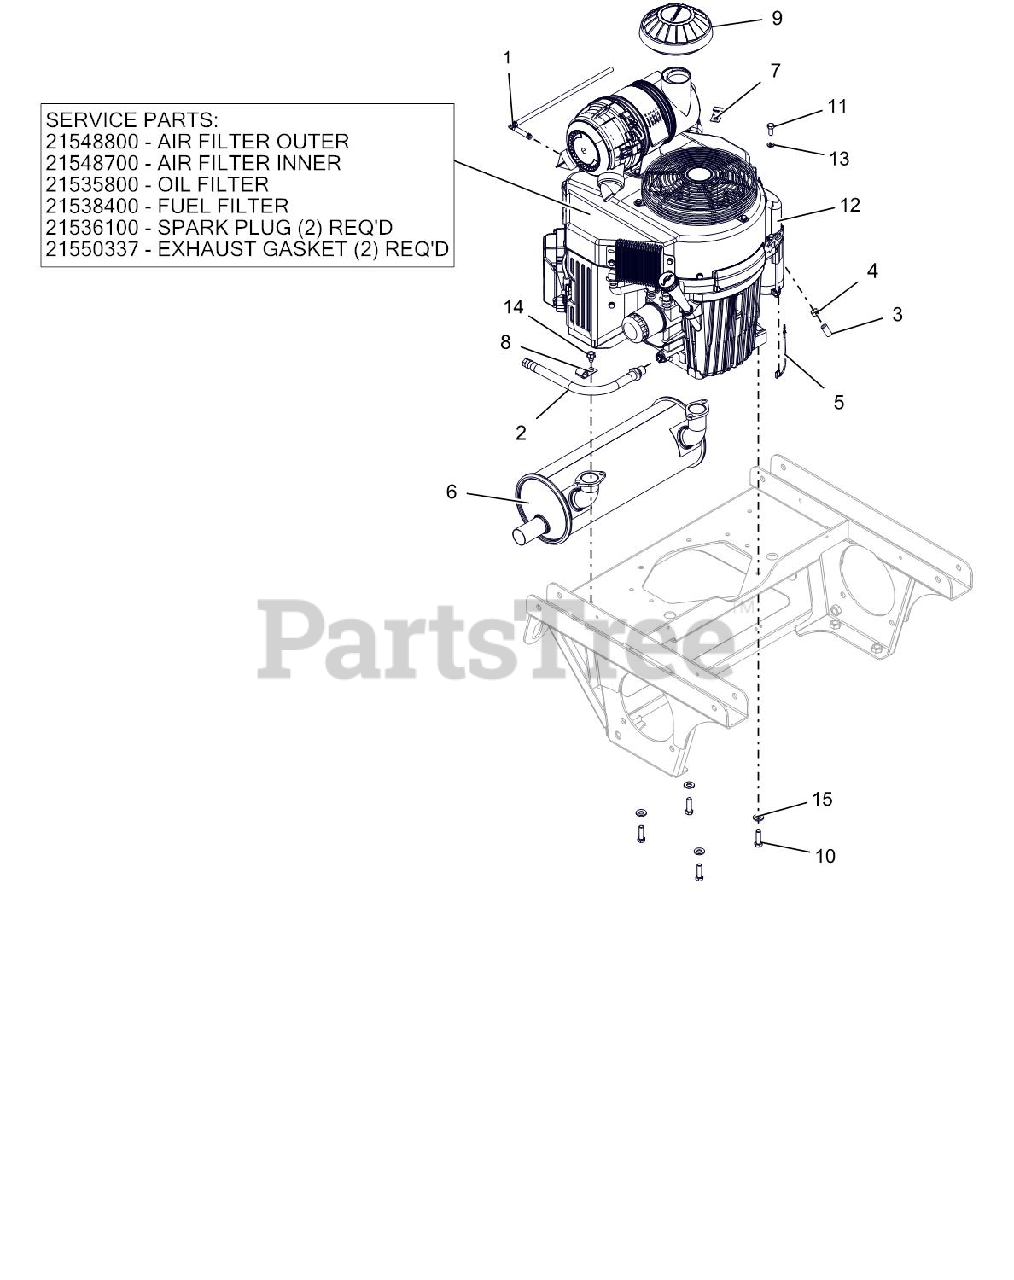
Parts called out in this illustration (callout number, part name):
1	ASM, VAPOR LINE
2	HOSE, OIL DRAIN
3	HOSE, .25 LOW-PERM BULK GAS
4	CLAMP, FUEL LINE
5	LEAD - STARTER SOLENOID
6	MUFFLER - 34HP KAWASAKI VERT.
9	CAP, AIR CLEANER INTAKE (2")
10	BLT-HEX.38-16X1.25 G5YZ NYTORQ
11	@BLT-HEX M8-1.25X20 YWZC
12	FILTER,OIL - KAW
12	PLUG, SPARK
12	FUEL FILTER - KAWASAKI
12	FILTER, OUTER
12	FILTER, INNER - KAW
12	ENGINE - KAWASAKI FX1000
12	GASKET, EXHAUST (11061-7061)
13	@WSHR-LK .31X.078 REG YWZC
14	@SCR-TAP .38-16X.50 HWH TR YWZ
15	WASHER, 3/8" SPRING DISC
